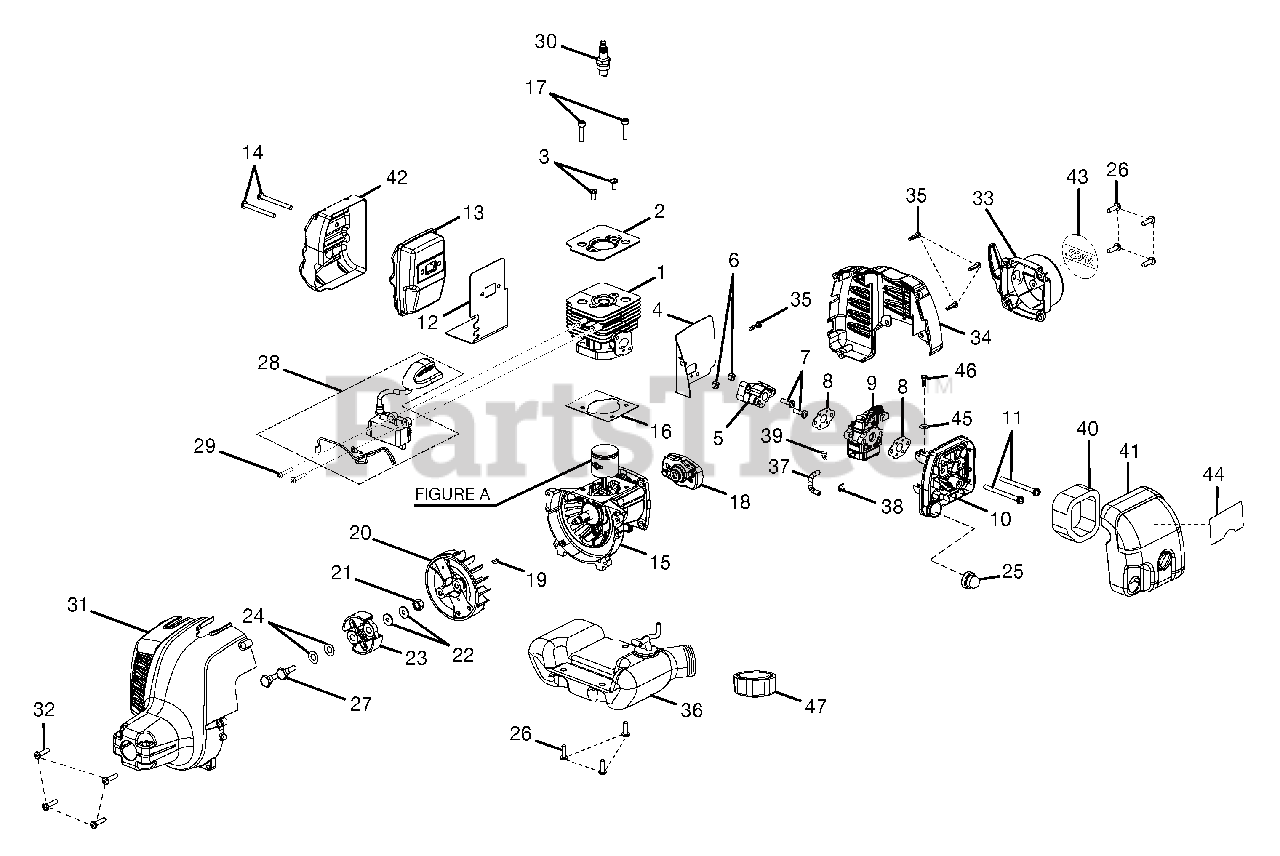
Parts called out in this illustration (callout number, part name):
1	25.4 CYLINDER
3	SCREW (M5 x 10 mm PAN HD.)
5	INSULATOR
6	NUT (M5 x .8 mm)
7	SCREW (M5 x 31 mm PAN HD.)
8	GASKET
9	CARBURETOR ASSEMBLY
10	FILTER HOUSING ASSEMBLY
11	SCREW (M5 x .8 x 60 mm PAN HD.)
12	GASKET
13	MUFFLER ASSEMBLY
14	SCREW (M5 x .8 x 50 mm PAN HD.)
15	CRANKCASE ASSEMBLY
16	GASKET
17	SCREW (M5 x .8 x 22 mm)
18	PULLEY ASSEMBLY
19	WOODRUFF KEY
20	ROTOR
21	NUT
22	WASHER
23	CLUTCH ASSEMBLY
24	WASHER, CURVED
25	PRIMER
26	SCREW (M5 X 16 mm)
27	SCREW (M6 x 1 x 14 mm PAN HD.)
28	COIL ASSEMBLY
29	SCREW (M4 x .7 x 22 mm PAN HD.)
30	SPARK PLUG
31	FRONT HOUSING ASSEMBLY
32	SCREW (M5 x .8 x 20 mm PAN HD.)
33	STARTER HOUSING ASSEMBLY
34	REAR ENGINE HOUSING
35	SCREW (M4 x 1.75 x 16 mm PAN HD.)
36	FUEL TANK
37	FUEL LINE
38	CLIP
39	CLIP
40	AIR FILTER
41	OUTER COVER ASSEMBLY
42	HEAT SHIELD
43	LOGO LABEL
44	PRIMER LABEL
46	SCREW (M4 X 16 mm TORX PAN HD.)
